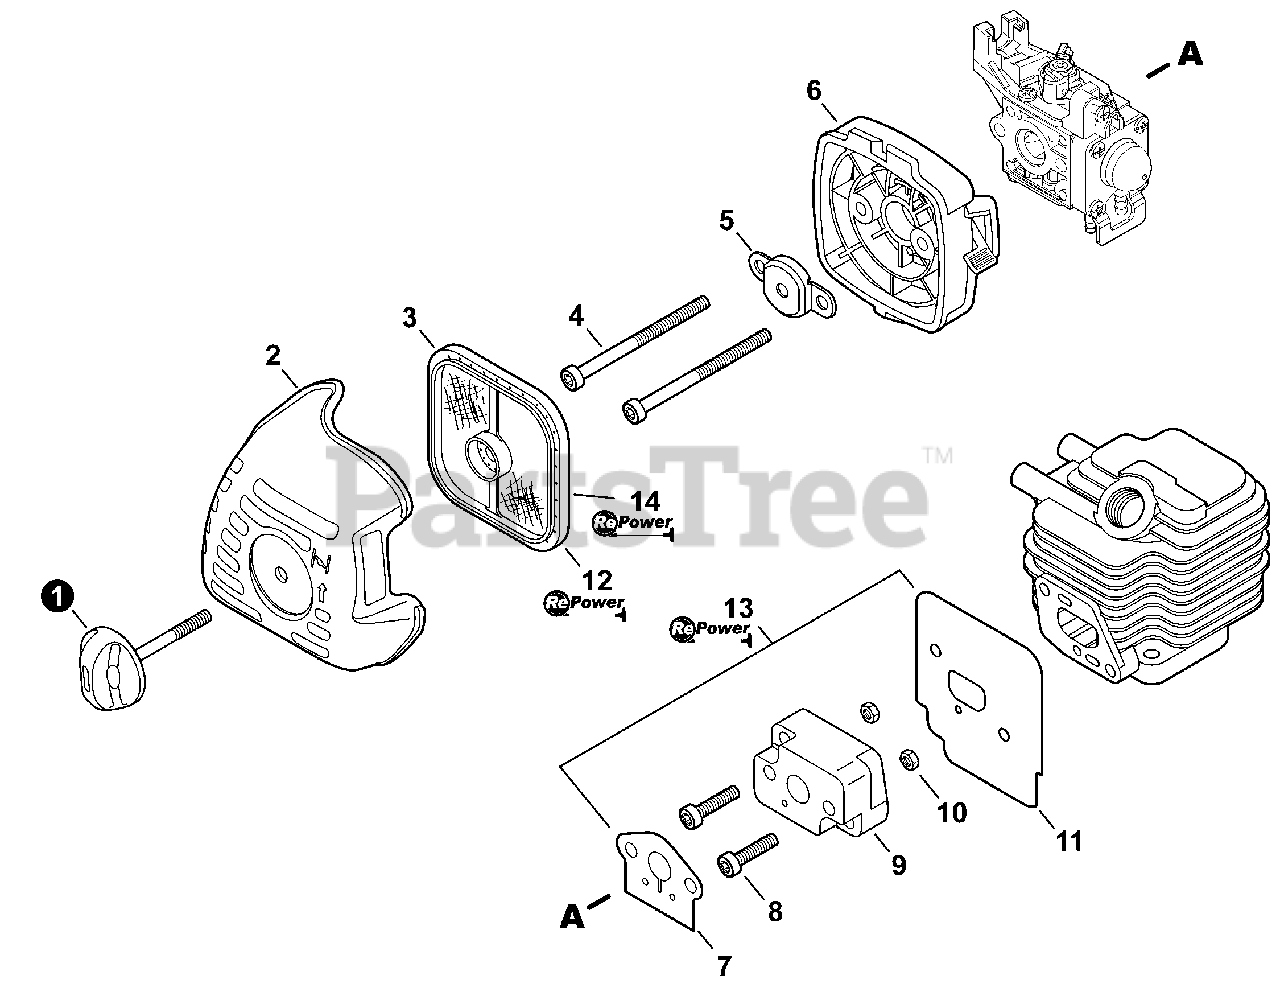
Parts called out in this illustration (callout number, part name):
1	THUMBSCREW
2	COVER, AIR FILTER
3	FILTER, AIR - DOUBLE LAYER
4	BOLT, TORX 5×65
5	PLATE, PREVENT
6	CASE ASSY, AIR FILTER
7	GASKET, INTAKE
8	BOLT, TORX 5×20
9	INSULATOR, INTAKE
11	GASKET, INTAKE
12	TUNE-UP KIT - REPOWER
13	GASKET KIT
14	FILTER KIT - REPOWER
